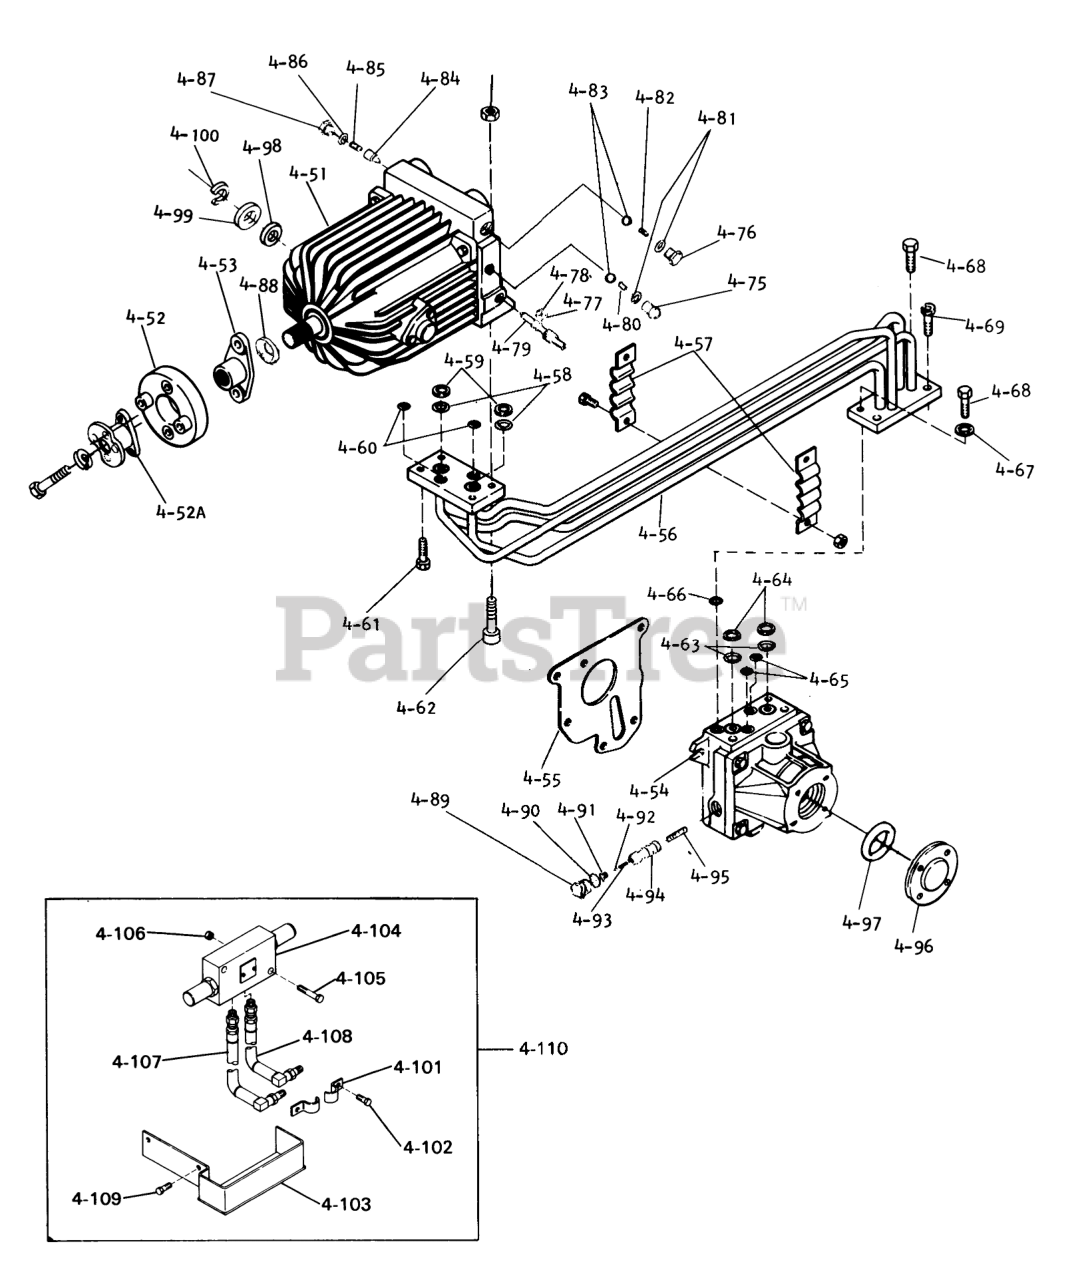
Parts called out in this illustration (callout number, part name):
4-51	Spring
4-52	Coupling
4-52A	Coupling, D-160 Only
4-53	COUPLING DRIVEN R
4-54	Hydro Motor Only
4-55	GASKET
4-56	Manifold, Hydraulic
4-57	Clamp
4-58	O RING
4-59	RING BACKUP
4-60	O RING
4-61	Bolt
4-62	Screw
4-63	O RING
4-64	RING BACKUP
4-65	O RING
4-66	O RING
4-67	SEAL-MANIFOLD BOLT
4-68	Bolt
4-69	Bolt 3/8-16 X 1
4-75	PLUG
4-76	Plug
4-77	Back Up Ring
4-78	O-RING
4-79	VALVE
4-80	Spring
4-81	O RING
4-82	Spring Chg. Rel. Valve
4-83	Ball
4-84	Cone
4-85	Spring-Implement Valve
4-86	O RING
4-88	SEAL
4-90	O-RING
4-91	Valve
4-93	SPRING
4-94	Sleeve
4-95	Spring
4-96	Plate
4-97	O-RING
4-98	SEAL
4-99	WASHER-LAMBERT
4-100	RING-LAMBERT
4-101	BRACKET
4-102	Bolt
4-103	Capscrew
4-104	Relief Valve
4-105	Bolt
4-106	NUT
4-107	HOSE-HYDRAULIC FRONT
4-108	ASSY-HYD HOSE FRONT
4-109	BOLT
4-110	Relief Valve Kit-S.A.
